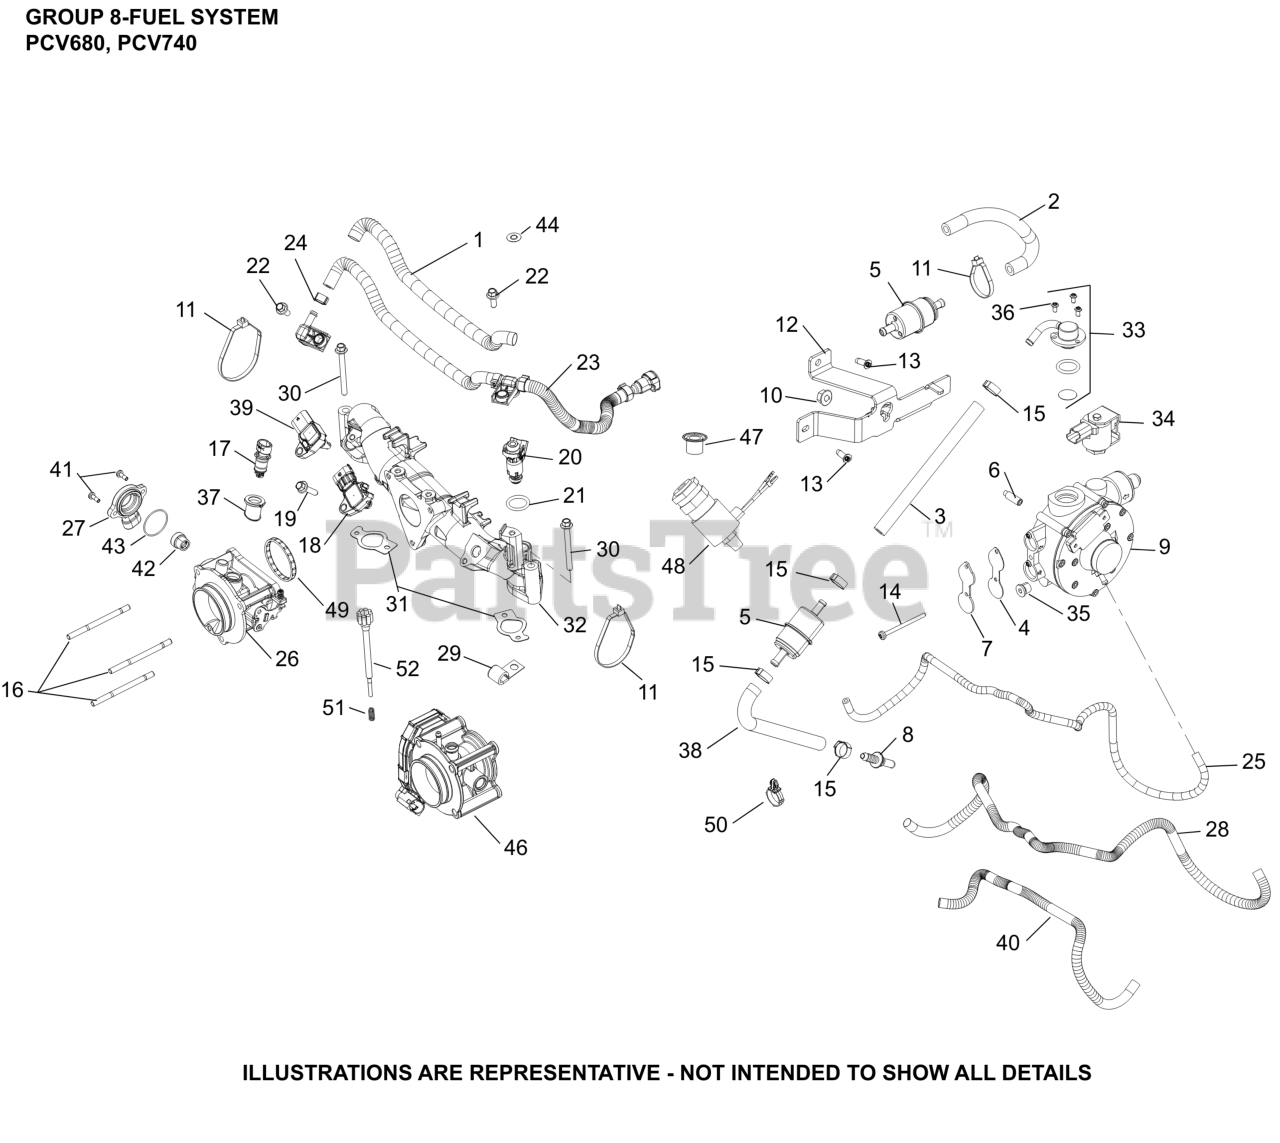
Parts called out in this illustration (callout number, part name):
1	SLEEVE, ANTI ABRASION -USE 25 431 12-S
2	HOSE, FUEL LOW PERMEATION
3	HOSE, FUEL LOW PROPANE
5	PROPANE FUEL FILTER-(#2505050S)
5	PROPANE FUEL FILTER KIT
6	STUD, LP REGULATOR
7	COVER, OIL PORT
8	FITTING, FUEL - STRAIGHT
9	REGULATOR, W/RTV
10	NUT, FLG M8X1.25
12	BRACKET, LP REGULATOR
13	SCREW, THREAD FORMING
15	CLAMP, HOSE
16	STUD,M6X1.0X84
20	INJECTOR, GASEOUS FUEL
21	KIT, FUEL INJECTOR O-RING
22	SCREW, FLG M6x1.0x20
23	FUEL HOSE ASSY(ECV,FCV,EZT,EKT,PCH,PCV)
25	HOSE, EVAPORATIVE
26	BODY, THROTTLE ASM W/ PIN (30)
27	SENSOR, THROTTLE POSITION
30	SCREW, FLG M6X1.0X40
30	SCREW, FLG M6X1.0X60
31	KIT, INTAKE MANIFOLD GASKET
32	KIT, MANIFOLD
33	KIT, OUTLET FITTING W/O-RING LPG
34	KIT, LOCK-OFF ASSY LPG (A7-175)
35	KIT, PLUG W/O-RING LPG (A7-173)
36	SCREW, STARTER SWITCH
39	SENSOR, T-MAP
40	SLEEVE, ANTI-ABRASION
40	SLEEVE, ANTI ABRASION
42	MAGNET ASSEMBLY, TPS
43	O-RING, TPS SENSOR
44	CLIP, RETAINER
49	O-RING, THROTTLE BODY
50	RETAINER, WIRE HARNESS
51	SPRING, SPEED CONTROL (SHORT)
52	CABLE, IDLE ADJUSTMENT
NI	KIT, VAPORIZER FILTER REPL'MT LPG(A7-170
